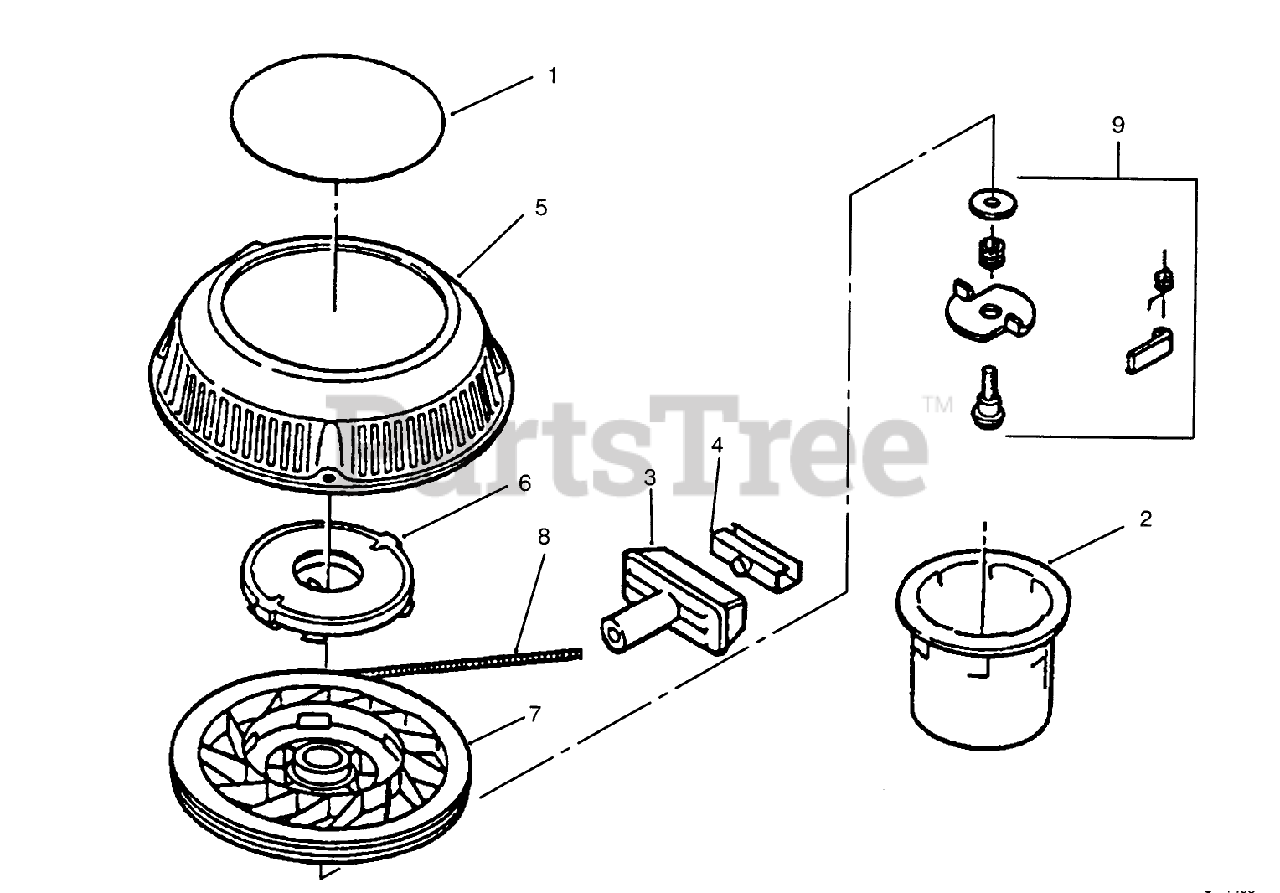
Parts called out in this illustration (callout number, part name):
2	HUB-STARTER E COMM.
4	CLIP-STARTER
5	STARTER HOUSING & SHAFT
6	SPRING KEEPER ASM
9	DOG KIT
